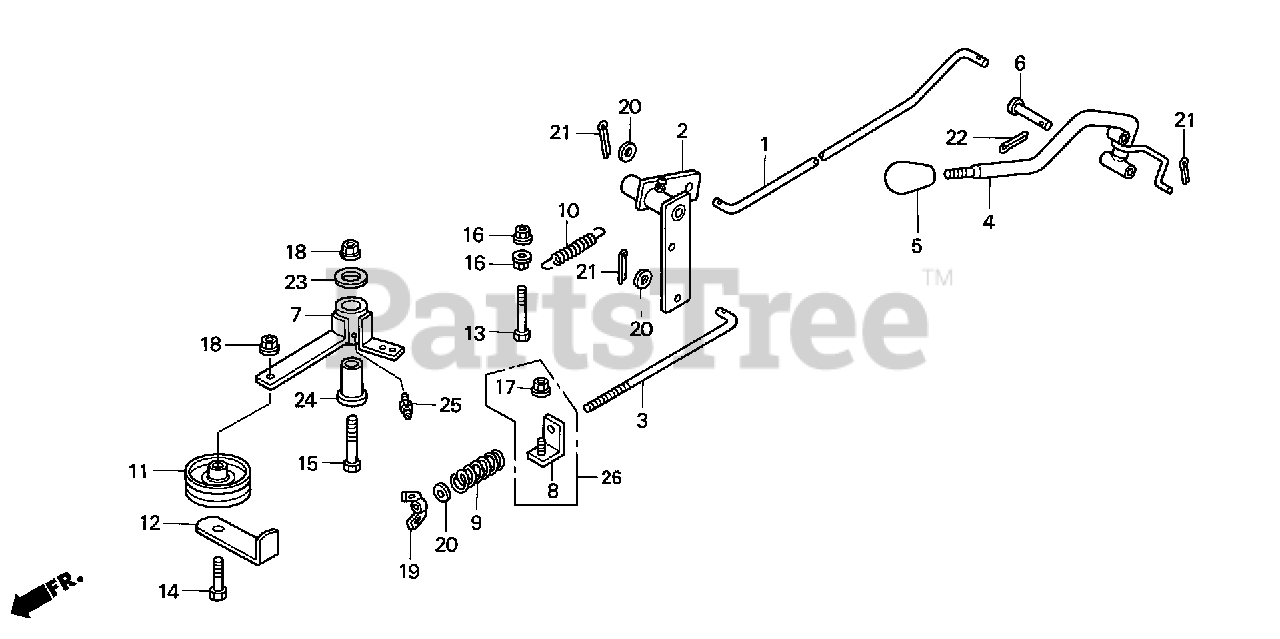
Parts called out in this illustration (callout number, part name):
1	ROD A, P.T.O.
2	ARM, P.T.O.
3	ROD B, P.T.O.
4	LEVER, P.T.O.
5	GRIP, P.T.O. LEVER
6	PIN, CLEVIS (3/8"X2 1/2")
7	ARM, TENSION
8	KIT, BRAKE BLADE
9	SPRING, TENSIONER ARM
10	SPRING, P.T.O. RETURN
11	ROLLER, TENSIONER
12	STOPPER B, BELT
13	BOLT, HEX. (1/4-20X1 1/4")
14	BOLT, HEX. (3/8-16X2 1/4")
15	BOLT, HEX. (3/8-16X3")
16	NUT, WHIZ-LOCK (1/4"-20)
17	NUT, WHIZ-LOCK (5/16"-18)
18	NUT, WHIZ-LOCK (3/8"-16)
19	WINGNUT (5/16-18)
20	WASHER, FLAT (5/16")
21	PIN, COTTER (3/32" X 3/4")
22	PIN, COTTER (1/8X3/4")
23	BUSHING (1")
24	BUSHING, PIVOT
25	NIPPLE, GREASE
26	KIT, BRAKE BLADE
